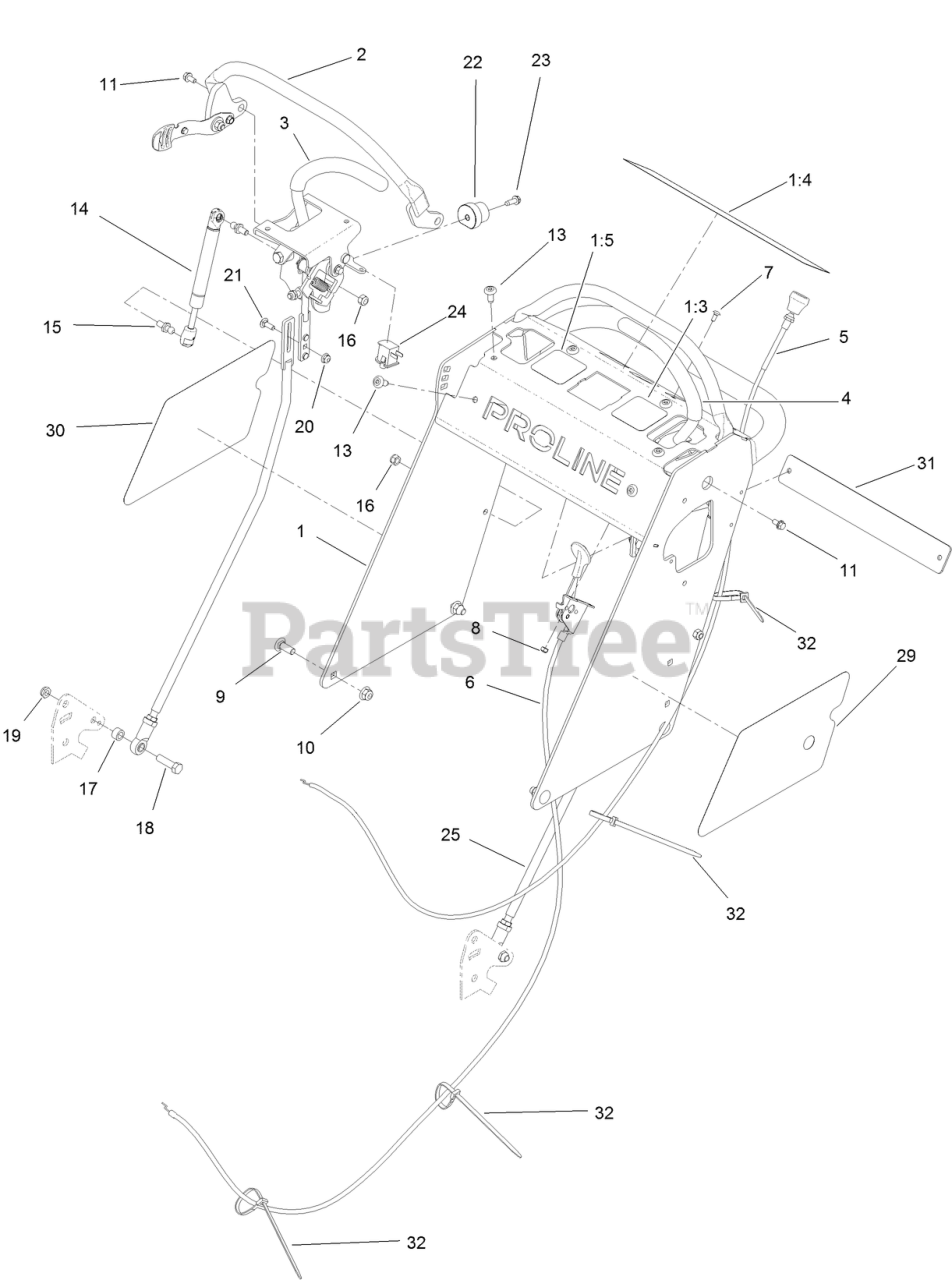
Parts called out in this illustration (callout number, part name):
1	TOWER ASM
1:3	DECAL-OPC CONTROL, LEFT
1:4	DECAL-WARNING, CONTROL
1:5	DECAL-OPC CONTROL, RIGHT
2	REFERENCE BAR ASSEMBLY
3	CONTROL HANDLE ASM, RH
4	CONTROL HANDLE ASM, LH
5	CABLE, CHOKE
6	CONTROL-THROTTLE
7	BOLT-CARR
8	NUT-LOCK, NI
9	SCREW-CARR
10	NUT-HF, NI
11	SCREW-HWH
14	DAMPER
15	STUD-BALL
16	NUT-LOCK, NI
17	SPACER
18	SCREW-HH
20	NUT-HF
21	BOLT-CARR
23	SCREW-HWHTF
24	SWITCH-BAIL
25	CONTROL ROD ASM
29	DECAL-PROLINE HDX, LH
30	DECAL-PROLINE HDX, RH
31	PLATE-COVER
32	TIE-PLASTIC
